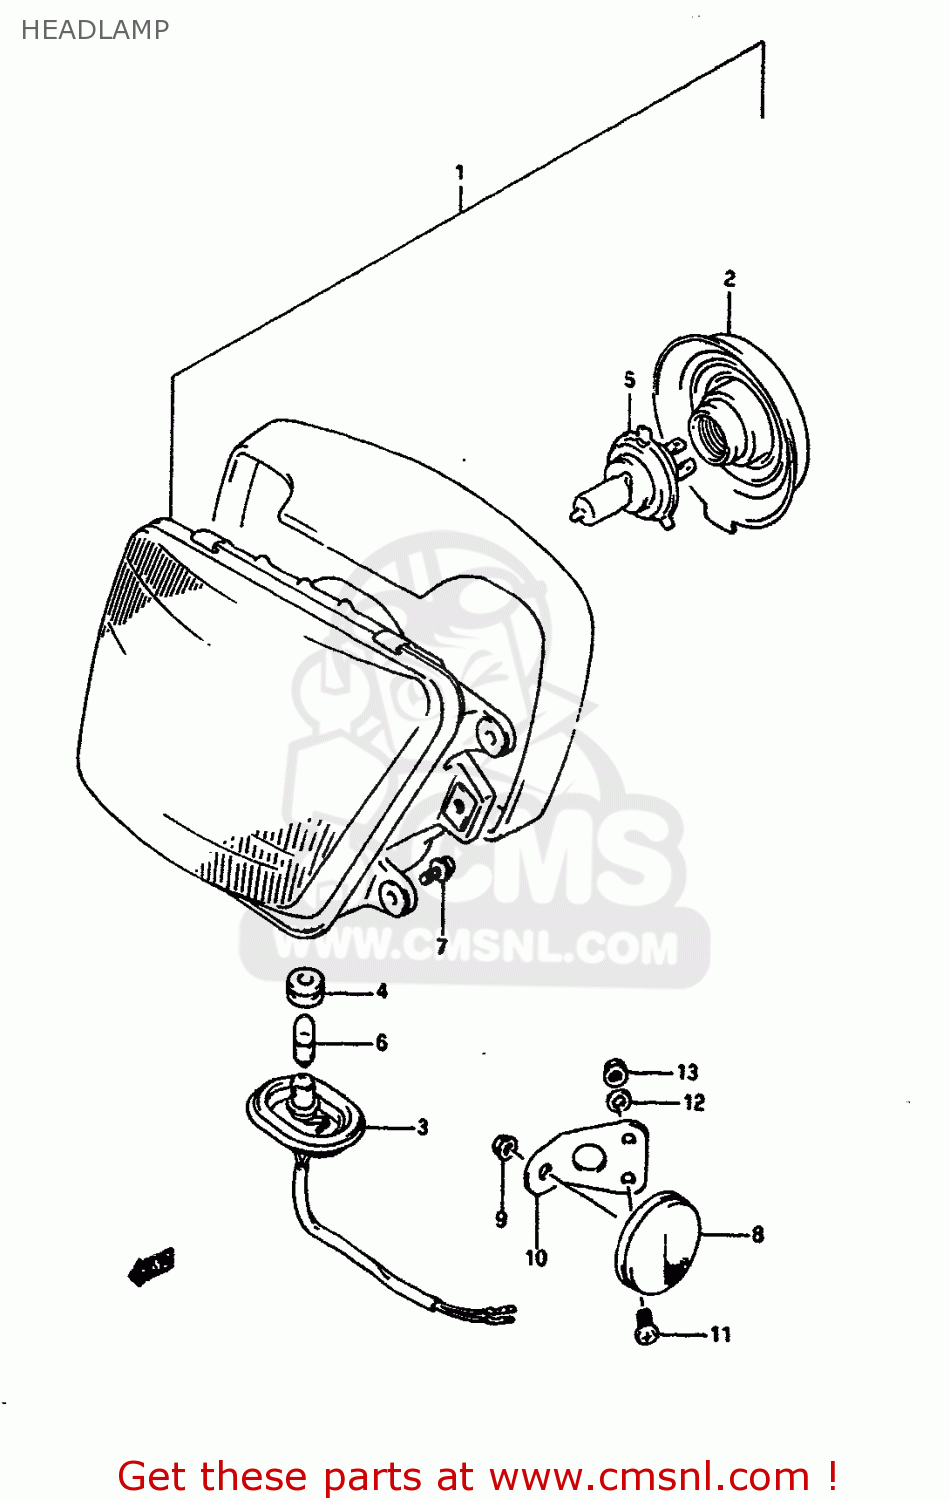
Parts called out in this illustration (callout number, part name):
1	HEADLAMP ASSY
2	COVER,SOCKET
3	SOCKET
4	JOINT,RUBBER
5	BULB(12V60/55W,H4)
6	BULB(12V4W)
7	SCREW
8	REFLECTOR,REFLEX FR
9	NUT ,5MM
10	BRACKET,FRONT SIDE RH
11	SCREW
12	WASHER (4X14X1.2)
13	NUT
